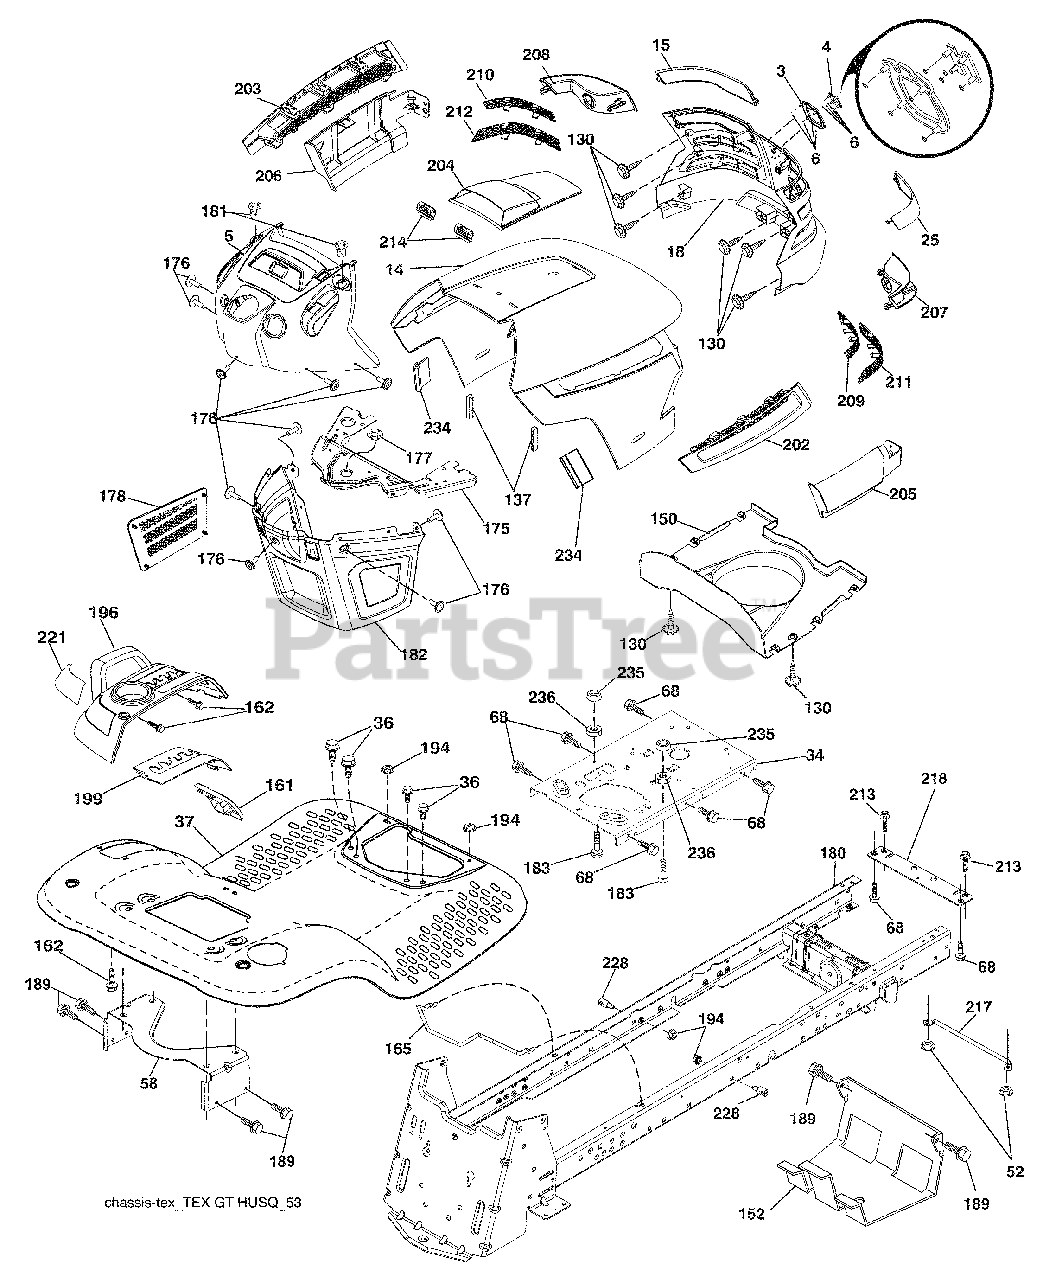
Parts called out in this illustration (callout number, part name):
3	Trim, Husq.
4	Logo
14	Hood
18	Grille/Lens Asm.
34	Plate Engine
36	Screw 5/16-18 x 3/4
37	Fender
52	Nut Lock 5/16-18
58	Bracket Support Fender
68	Screw Thdrol 5/16-18 x 1/2
130	Screw 10 x .750 BOS Thread
137	Bumper Dash
152	Shield Browning
161	Window, Fuel
162	Screw Hex Wsh 1/4 x 1/2 unc
165	Support Tank Rear
175	Crossmember
176	Screw 10-24 x 5/8
177	Bushing Steering
178	Cargo Net Asm.
180	Chassis
181	Bushing Mtg. Fender Crgo
182	Dash Lower
183	Bolt Fin Hex 5/16-18 unc x 1-1/4
189	Screw 5/16-18 x 3/4
194	Nut Lock Hex Flange 5/16-
196	Console Asm. Deck Lift
199	Plate Deck Lift
202	Vent Side Hood RH
203	Vent Side Hood LH
204	Vent Top Hood
205	Skirt Hood Side RH
206	Skirt Hood Side LH
209	Insert Hex Top RH
210	Insert Hex Top LH
211	Insert Hex Bottom RH
212	Insert Hex Bottom LH
213	Bolt 5/16-18 x 3/4
214	Clip Retainer Tinner
218	X-Piece Hood Stop
221	Reflector LH
228	Stud Fastner
233	Bolt, Shoulder
234	Bumper Hood
235	Spacer Fender
236	Nut Lock 5/16-18 unc
